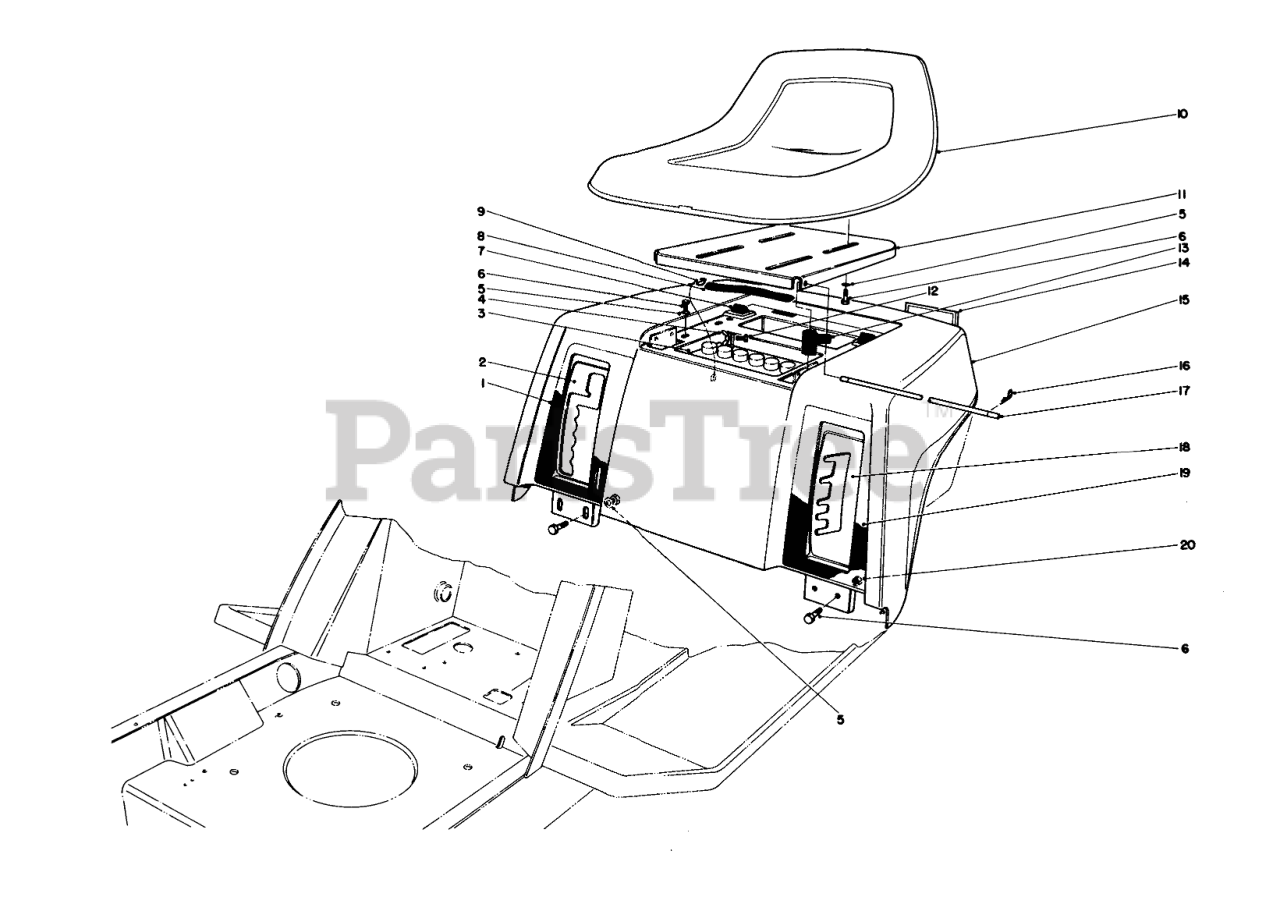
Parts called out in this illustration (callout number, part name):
1	Decal Transmission
2	DETENT PLATE B
3	BATTERY-DRY W/CARTON
4	NUT-WING
5	WASHER-PLAIN
6	SCREW-HH
7	SEAT BUMPER
8	Battery Strap
10	Seat (Model #57351)
11	Seat Support
12	SCREW-HH
13	BOOT-TERMINAL
14	REFLECTOR
15	Rear Body
16	PIN-COTTER
17	PIVOT-SEAT
18	Quadrant Height of Cut
19	Decal Height of Cut
20	NUT-LOCK, CONE
